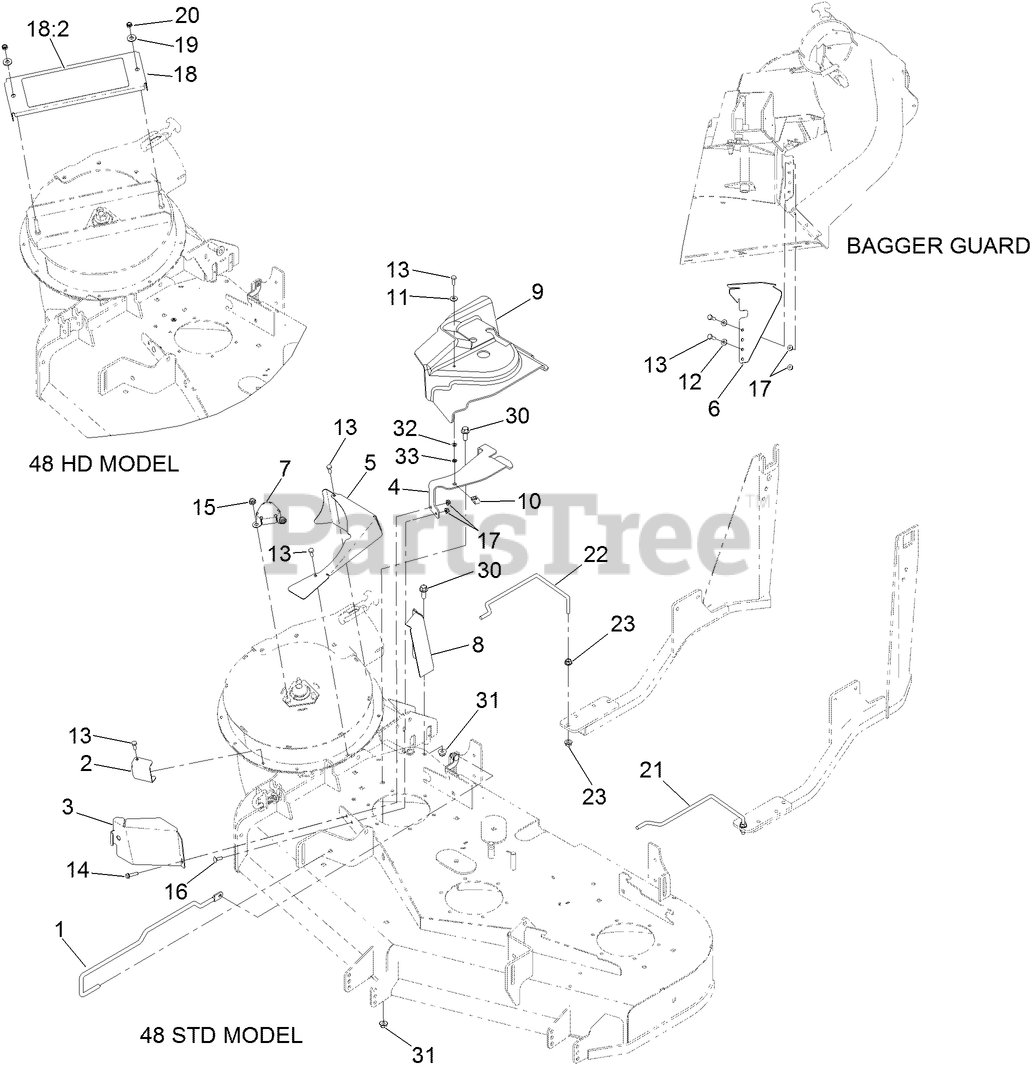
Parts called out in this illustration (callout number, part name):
1	ROD-SUPPORT, LOWER
2	GUARD-FRONT, LEFT
3	GUARD-BAGGER
4	BRACKET-COVER
5	GUARD-TOP
6	GUARD-BAGGER
7	COVER-NUT
8	GUARD-REAR
9	COVER-BELT
11	WASHER-FLAT
12	WASHER-FLAT
13	SCREW-HH
14	SCREW-HHF
15	NUT-HF
16	BOLT-CARR
17	NUT-HF
18	COVER-BEARING
18:2	DECAL-DANGER
19	WASHER-FLAT
20	NUT-LOCK, NI
21	ROD-SUPPORT, REAR (LH)
22	ROD-SUPPORT, REAR (RH)
23	NUT-HHF, WHIZ
30	SCREW-HHF
31	NUT-HF, NI
32	WASHER-FLAT
33	NUT-RETAINER
